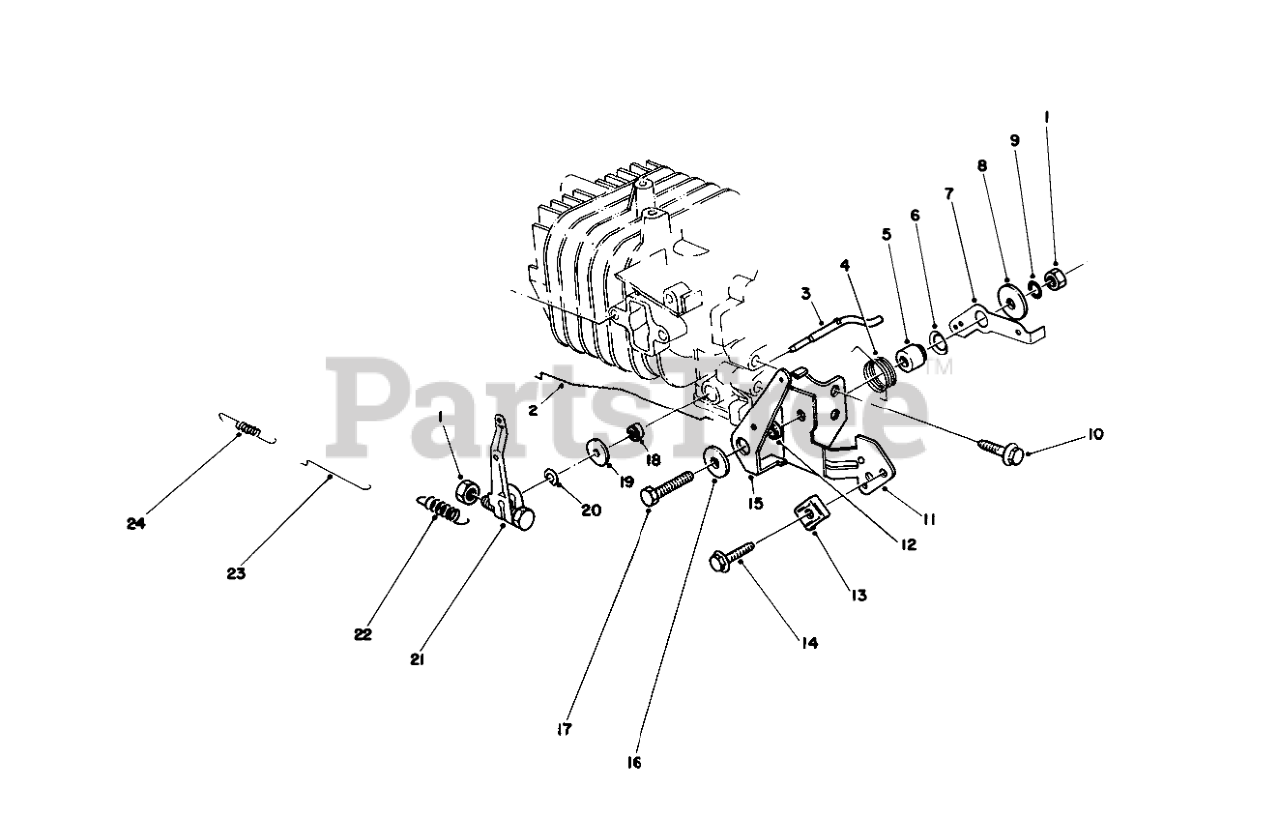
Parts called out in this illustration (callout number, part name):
2	CHOKE ROD
3	Shaft-Govemor
4	SPRING-CHOKE LEVER
5	Gov Lever Spacer
6	Washer-Gov. Spring Lever
7	LEVER-SPRING, GOVERNOR
8	WASHER
9	LOCKWASHER
11	BRACKET-THROTTLE, CONTROL
12	SPACER-CHOKE LEVER
13	CLAMP
15	LEVER-CONTROL, CHOKE
16	WASHER
18	SEAL-OIL
19	WASHER
20	E-RING
21	GOVERNOR ARM
22	SPRING-GOVERNOR
23	ROD-CARBURETOR
24	SPRING
